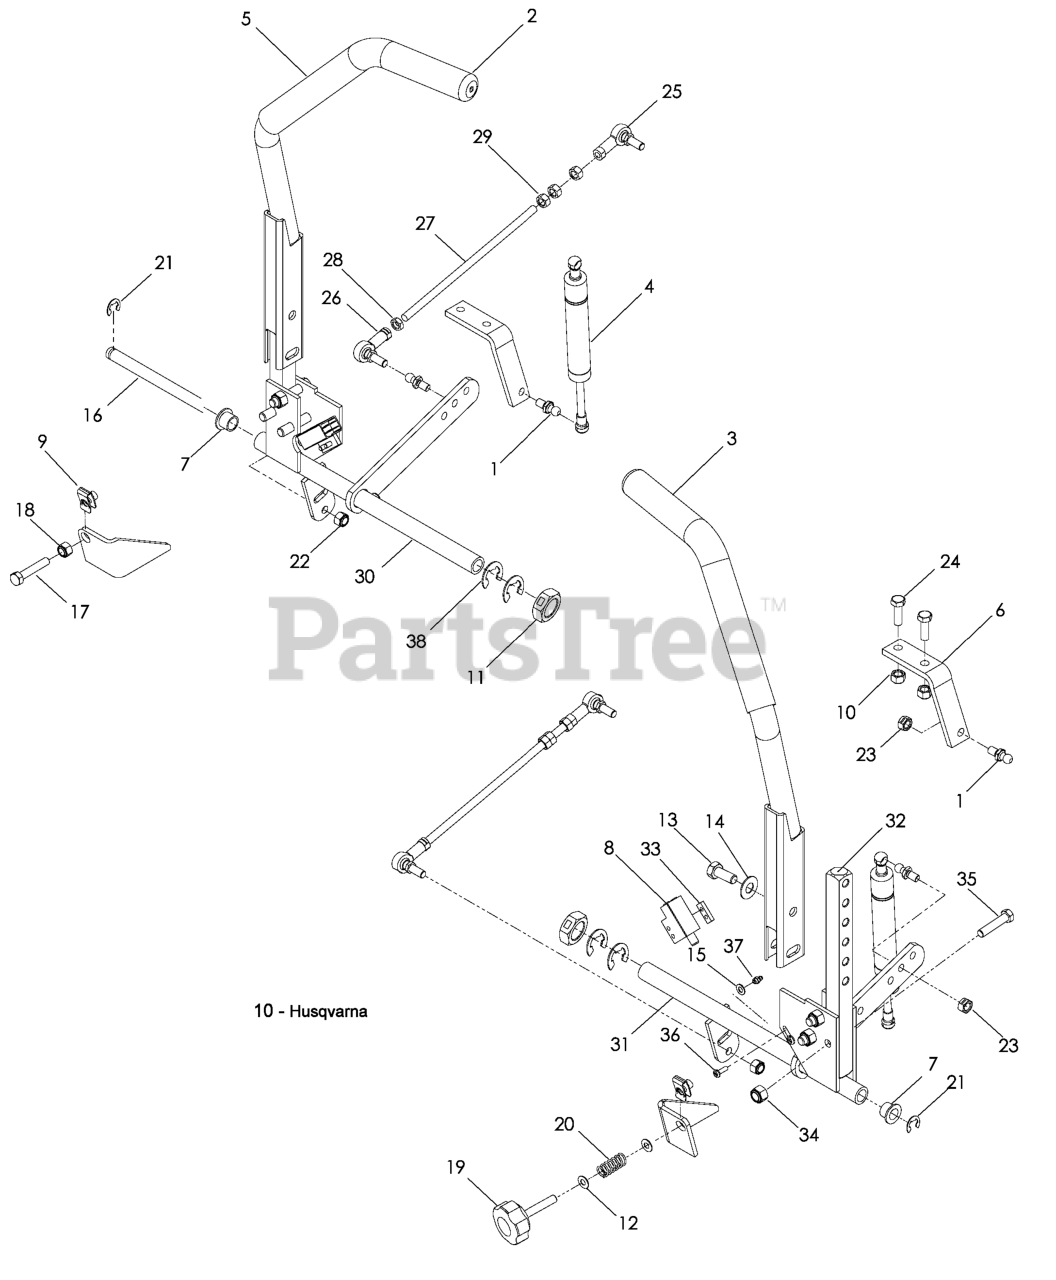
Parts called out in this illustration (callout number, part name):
1	STUD.BALL.10MM
2	ASSEMBLY, DRIVE LEVER RT
3	ASSEMBLY, DRIVE LEVER LT
4	DAMPENER W/EXT SEAL
5	GRIP - DRIVE LEVER 12"
6	DAMPENER BRACKET
8	SWITCH, INTERLOCK
9	U-CLIP 5/16-18 NUT RETAINER
10	NUT 5/16 NYLOC
11	NUT 3/4 X 16 HEX CTR
12	WASHER 5/16 FLAT
13	HCS 3/8-16X1.GRD.5.ZD
14	WASHER, 3/8 DISC SPRING SPEC
16	CONTROL SHAFT
17	HCS 5/16-18X1-3/4 TPBLT
18	NUT 5/16C HEX
19	ADJUSTMENT KNOB
20	COMPRESSION SPRING
21	E-RING 1/2 (2 2)
22	NUT 5/16F NYLOC
23	NUT 5/16C CENTERLOCK
24	HCS 5/16C X 1
25	SPHERICAL ROD END, RH
26	SPHERICAL ROD END, LH
27	PUMP CONTROL LINK
28	NUT 5/16F LEFTHAND
30	CONTROL ASM - ADJ, RT
31	CONTROL ASM - ADJ, LT
32	CONTROL ARM
33	TAPPED PLATE
34	NUT 3/8-16 NYLOC
35	HCS 3/8-16 X 1 3/4 GR5
36	SCREW #10-24 X 5/8
37	ZERK
38	E-RING 5/8
